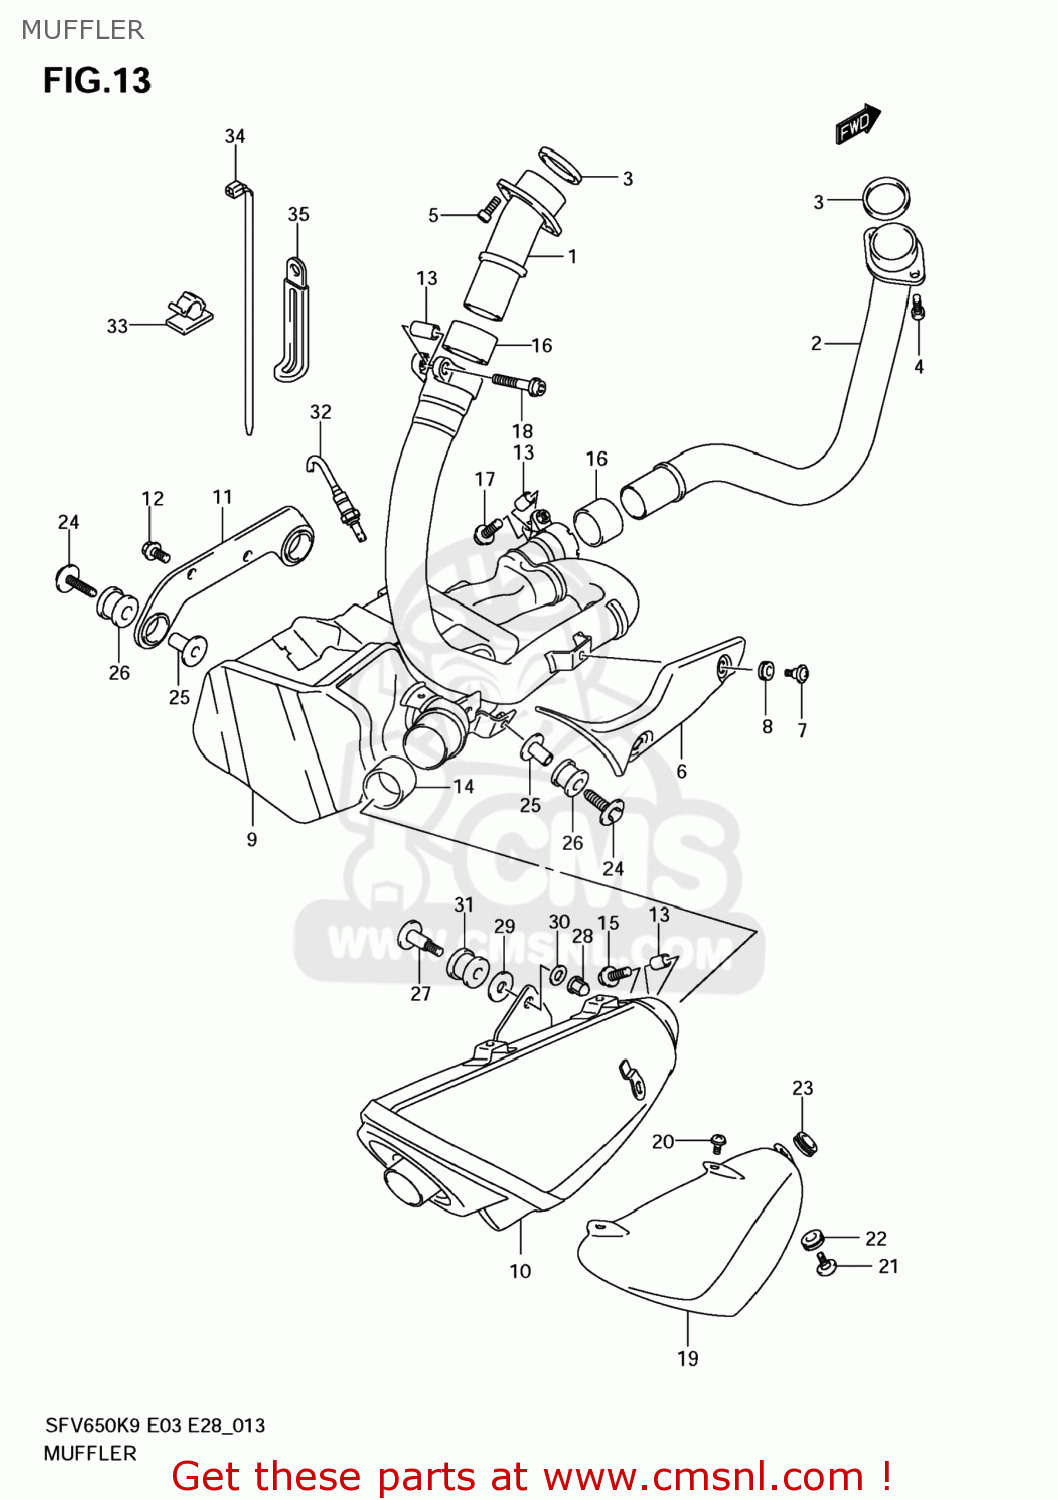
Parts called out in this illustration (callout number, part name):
1	PIPE,EXHAUST RR
2	PIPE,EXHAUST FR
3	GASKET,EXHAUST PIPE (NAS)
4	BOLT(8X25)
5	BOLT
6	COVER,EXHAUST
7	SCREW(6X12)
8	CUSHION
9	CHAMBER COMP
10	BODY,MUFFLER
11	BRACKET,MUFFLER SUPPORT
12	BOLT
13	SPACER,MUFFLER
14	CONNECTOR,MUFFLER
15	BOLT(8X35)
16	CONNECTOR,MUFFLER
17	BOLT(8X35)
18	BOLT(8X40)
19	COVER,MUFFLER
20	SCREW(6X10)
21	SCREW(6X12)
22	CUSHION
23	CUSHION
24	BOLT(8X40)
25	SPACER(8.6X12X24.2)
26	CUSHION
27	BOLT,MUF SPRT RR
28	NUT
29	WASHER(8.5X30X2.3)
30	WASHER(8.5X20X1.6)
31	CUSHION
32	SENSOR,OXYGEN
33	CLIP
34	CLAMP(L:165)
35	CLAMP(L:45)
